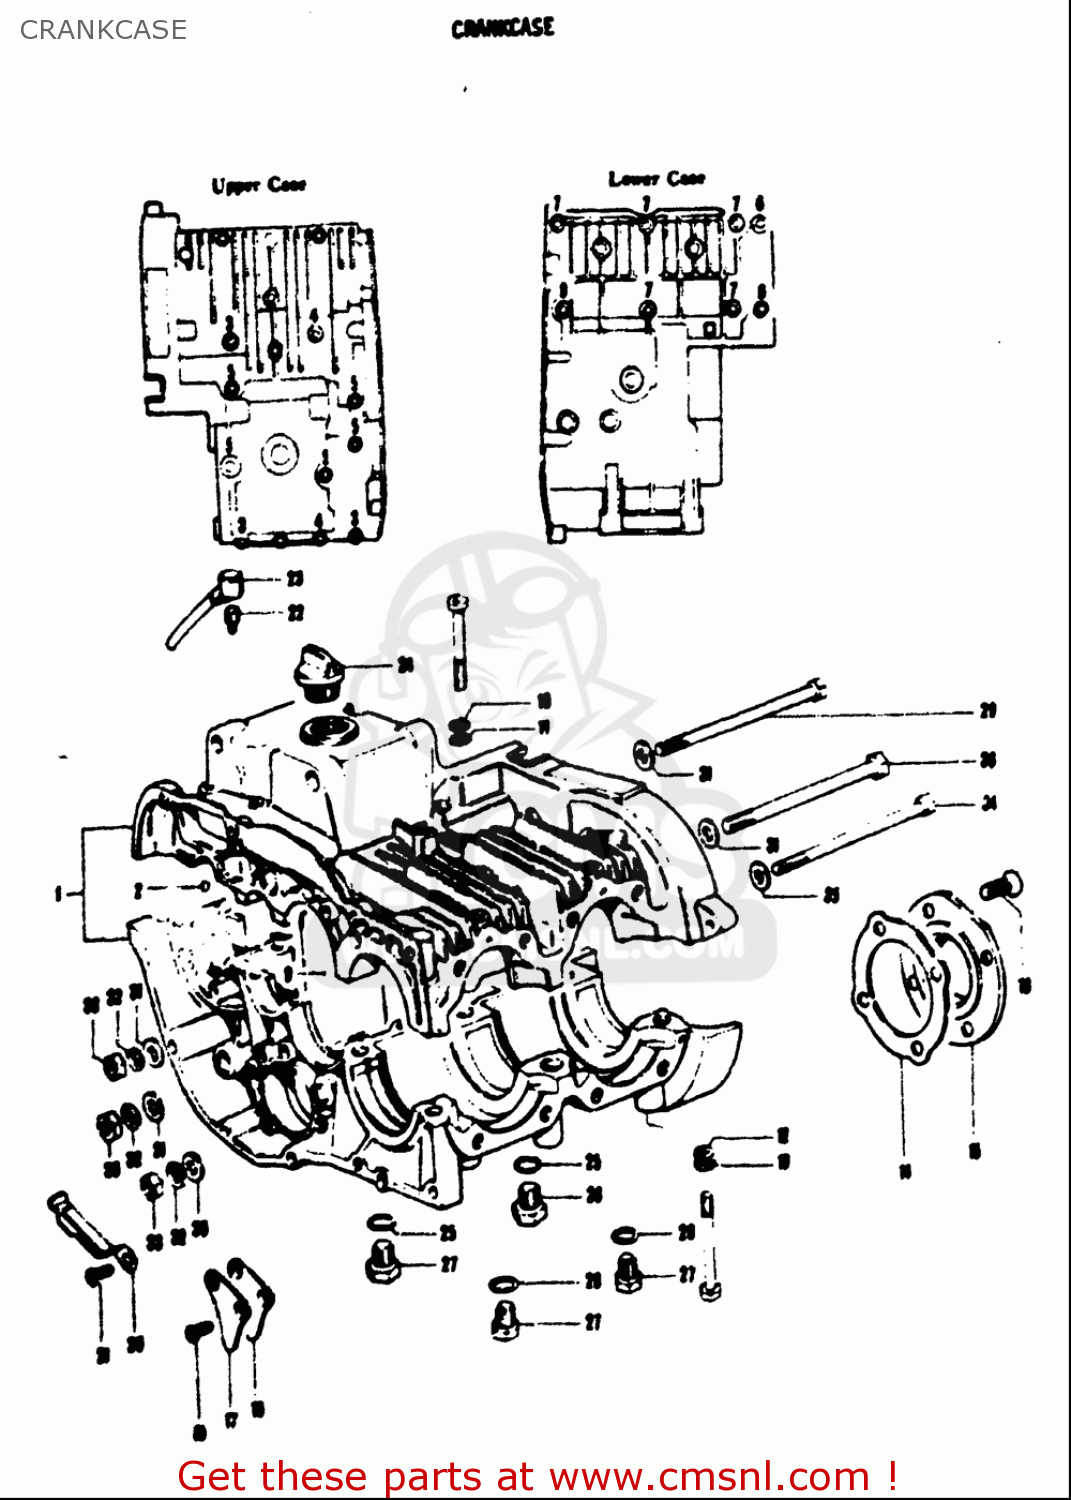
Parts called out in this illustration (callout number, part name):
2	PIN
3	BOLT
4	BOLT
5	BOLT
6	BOLT
7	BOLT
8	BOLT
9	WASHER,LOCK
10	WASHER
11	WASHER
12	WASHER,LOCK
16	SCREW
22	PLUG,T/M BREATHER
23	GASKET (NAS)
24	PLUG SET
25	GASKET(12X16X2) (NAS)
26	PLUG,12X9
27	PLUG
28	GASKET(10X14X3.6) (NAS)
29	BOLT 8X100
30	WASHER
31	WASHER,LOCK
32	NUT
34	WASHER
